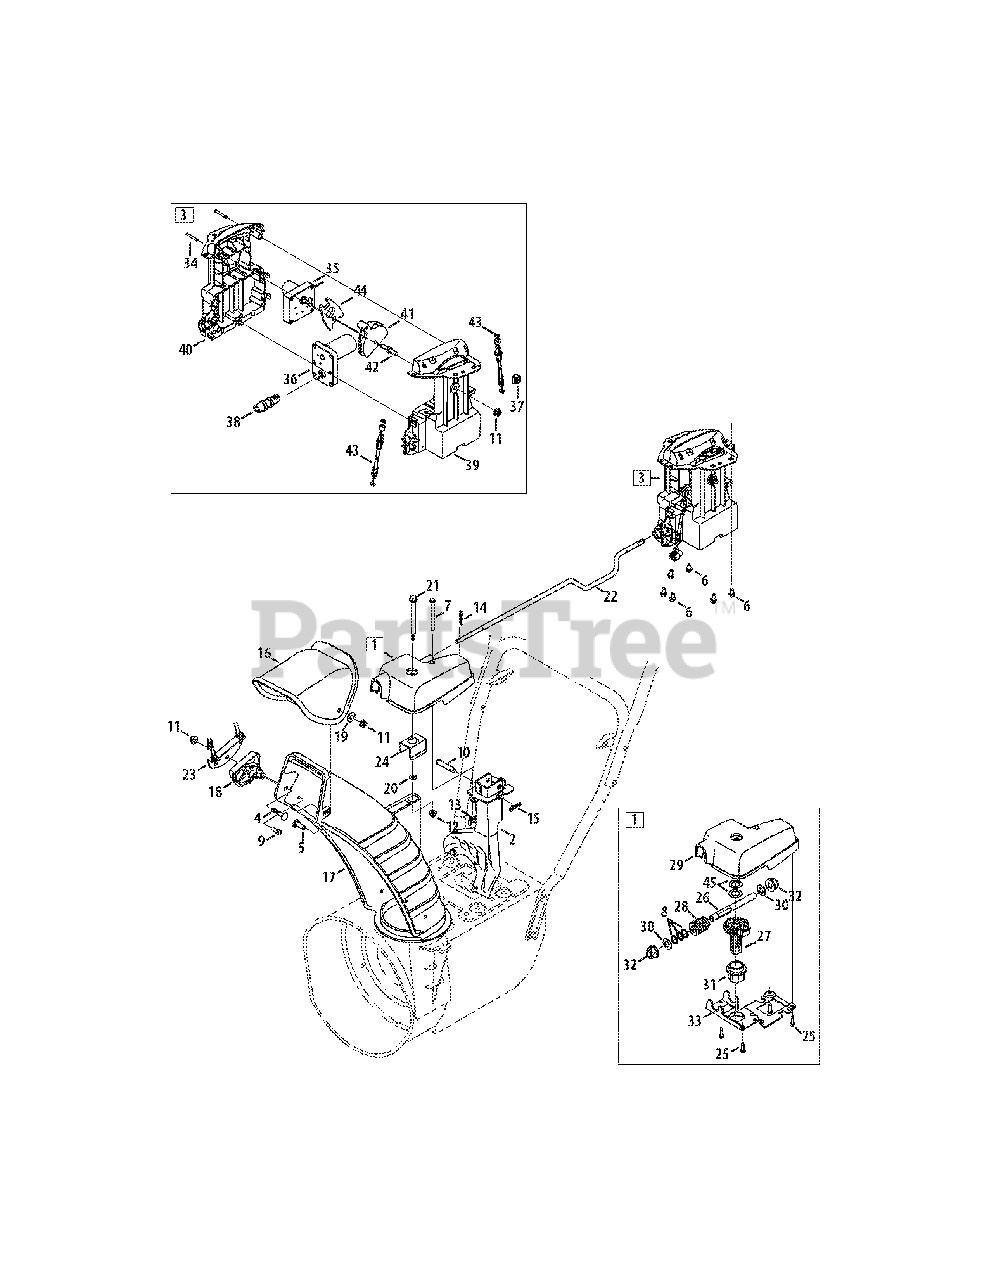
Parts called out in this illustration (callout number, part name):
1	Gearbox Assembly, Chute Rotation
2	Chute Support Bracket
3	Chute Assembly, 4-Way Elec.
4	Bolt, Carriage, 5/16-18 x 1.50
5	Bolt, Carrier, 5/16-18 x 1.00
6	Screw, HL, 1/4-15 x 0.50
7	Hex Head Screw, 1/4-20 x 3.00
8	Shim Washer, .504 x .700 x .010
9	Screw, HL, 1/4-15 x 0.750
10	Clevis Pin, 3/8 x 1.87
11	Nut, Flangelock, 5/16-18
12	Nut, Flangelock, 1/4-20
13	Wing Nut, 1/4-20
14	Internal Cotter Pin
15	Bow-Tie Cotter Pin
16	Chute, Upper
17	Chute, Lower
18	Cable Guide, Chute Tilt
19	Washer, Flat, .349 x .879
20	Washer, Flat, .25 x .630
21	Screw, Shoulder, .312 x 3.5 x 1/4-20
22	Chute Crank Rod
23	Cable Bracket
24	Chute Bracket
25	Screw, 12-16 x .75
26	Hex Shaft
27	Gear, 23 T
29	Gear Cover
30	Flat Washer, .510 x 1.00 x .060
31	Flange Bearing, 1.00 ID
32	Flange Bearing, .50 ID
33	Gear Bracket
34	Screw, #10-16 x 1.25
35	Chute Pitch Motor
36	Chute Rotation Motor
37	Cable Clip
38	Electric Chute Coupler
39	Housing, LH
40	Housing, RH
41	Cable Guide
42	Hex Screw, 5/16-18 x .75
43	4-Way Cable
44	Chute Pitch Adapter
45	Shim Washer, .632 x 1.00 x .010
